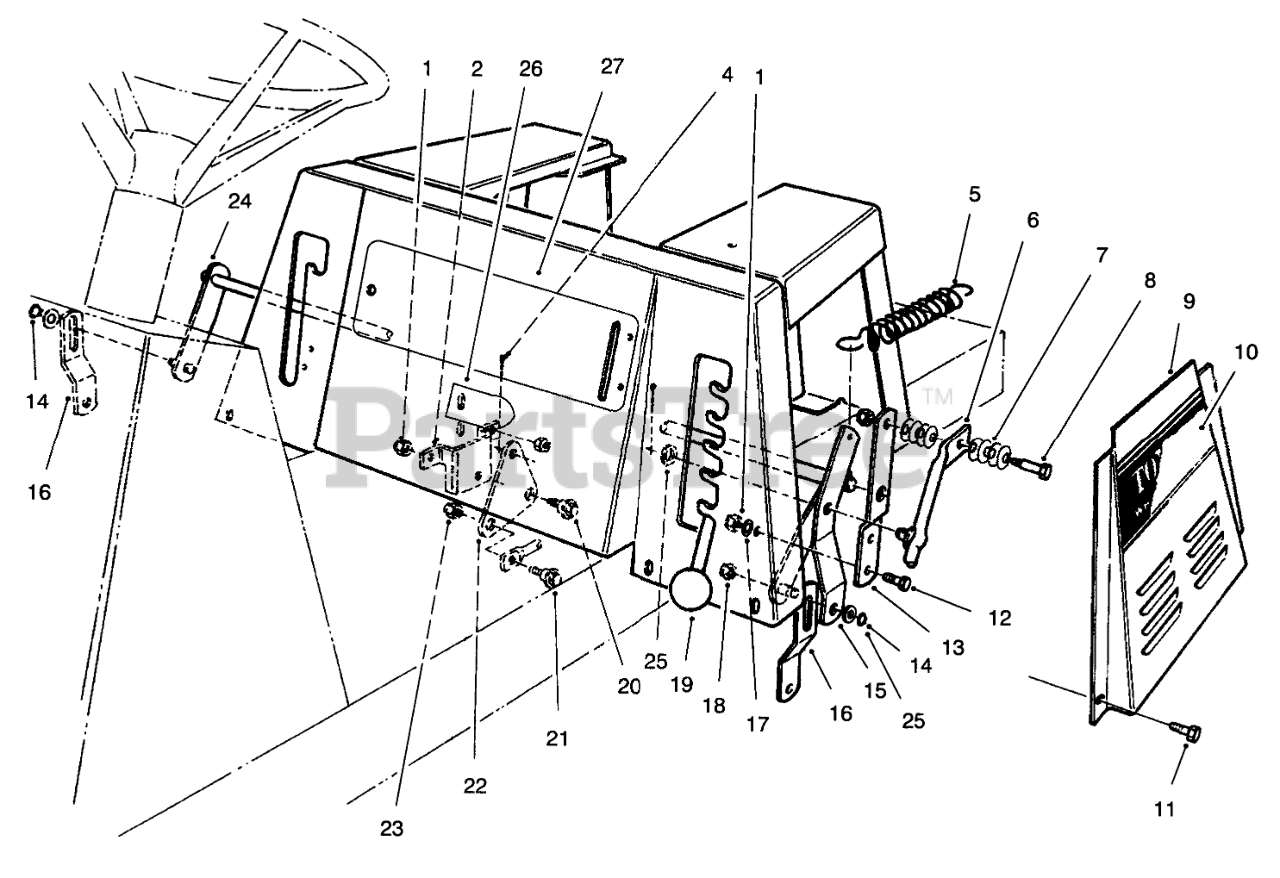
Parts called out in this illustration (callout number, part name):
1	NUT-LOCK, NI
2	BRKT-B.CRANK MTG
4	PIN-COTTER
5	SPRING-EXTENSION
6	HOC LEVER WA B
7	WASHER-BELLEVILLE
8	BOLT-SHOULDER
9	Panel L.H.-Base, Seat
10	DECAL - TORO 1332 LH
11	SCREW-HH
12	SCREW-HH
13	Bracket
14	RING-RETAINING
15	Bracket-H.O.C., Engage
16	Link-Deck Suspension
17	WASHER-PLAIN
18	NUT-LOCK, NI
20	SCREW-SHOULDER
21	SCREW-SHOULDER
22	BELLCRANK
23	NUT-HEX
24	Arm
25	WASHER-FLAT
26	DECAL - USA
27	DECAL - CONTROL PANEL
